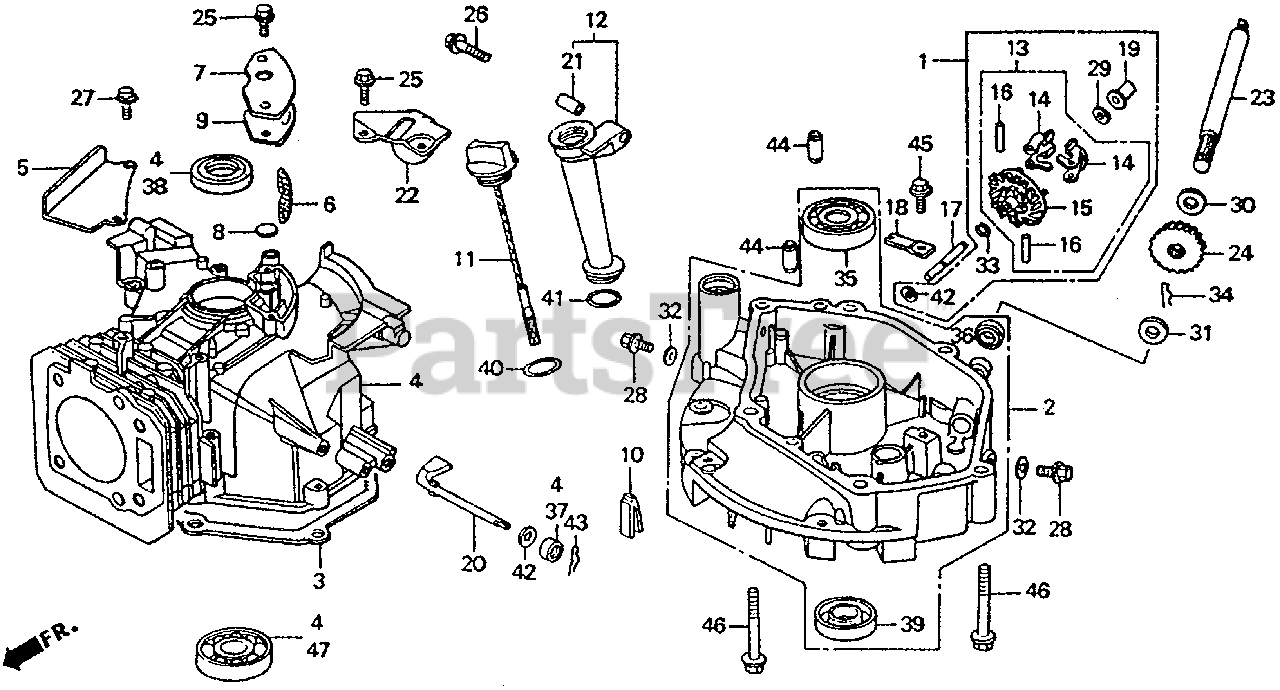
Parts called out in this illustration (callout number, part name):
1	GOVERNOR KIT
2	PAN ASSY., OIL
3	GASKET, OIL PAN
4	CYLINDER ASSY.
5	PLATE, GUIDE
6	FILTER, BREATHER
7	COVER, BREATHER
8	VALVE, BREATHER
9	GASKET, BREATHER COVER
10	RUBBER, OIL RETURN
11	GAUGE, OIL LEVEL Use up to Engine SN 1257294.
11	DIPSTICK, OIL Use up to Engine SN 1257294.
12	EXTENSION, OIL FILLER (NOT AVAILABLE) Use up to Engine SN 1257294.
12	EXTENSION, OIL FILLER (106MM)
13	GOVERNOR ASSY.
14	WEIGHT, GOVERNOR
15	HOLDER, GOVERNOR WEIGHT
16	PIN, GOVERNOR WEIGHT
17	SHAFT, GOVERNOR HOLDER
18	PLATE, GOVERNOR SHAFT HOLDER
19	SLIDER, GOVERNOR
20	SHAFT, GOVERNOR ARM
21	COLLAR, EXTENSION Use up to Engine SN 1257294.
22	STAY, TANK
23	SHAFT, DRIVE
24	GEAR, DRIVEN (22T)
25	BOLT, FLANGE (6X14)
26	BOLT, FLANGE (6X32)
27	BOLT, FLANGE (6X20) (CT200)
28	BOLT, DRAIN PLUG
29	WASHER, THRUST (6MM)
30	WASHER, THRUST (12MM)
31	WASHER (10X21)
32	WASHER, DRAIN PLUG (10.2MM)
33	CLIP, GOVERNOR HOLDER
34	PIN, LOCK (2.0)
35	BEARING, RADIAL BALL
36	OIL SEAL (12X20X5) (ARAI)
37	OIL SEAL (6X11X4)
38	OIL SEAL (25X38X7) (ARAI)
39	OIL SEAL (25.4X40X7)
40	O-RING (26X2.7)
41	O-RING (22.5X2.2) Use from Engine SN 1257295.
41	O-RING (22.1X2) Use up to Engine SN 1257294.
42	WASHER, PLAIN (6MM)
43	PIN, LOCK (8MM)
44	PIN A, DOWEL (8X14)
45	BOLT, FLANGE (6X12) Use from Engine SN 2086984.
46	BOLT, FLANGE (8X50)
47	BEARING, RADIAL BALL (6205)
